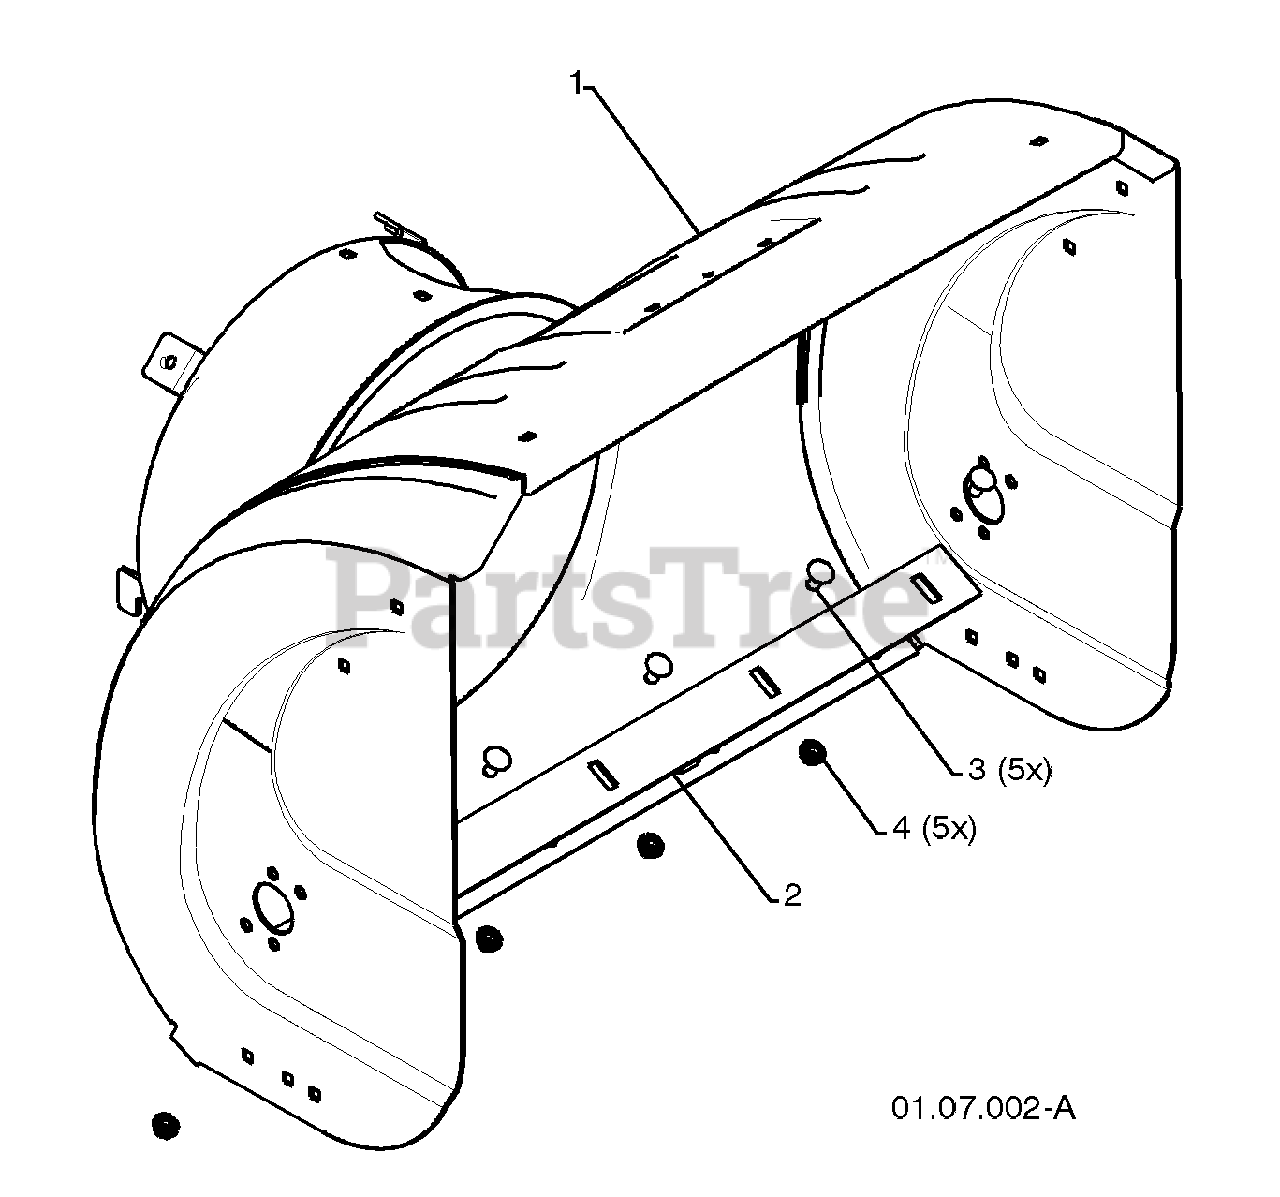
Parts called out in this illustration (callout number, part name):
1	AUGER HOUSING 27
2	SCRAPER BAR
3	CARRIAGE BOLT 5/16-18 X .625
4	NUT 5/16-18
